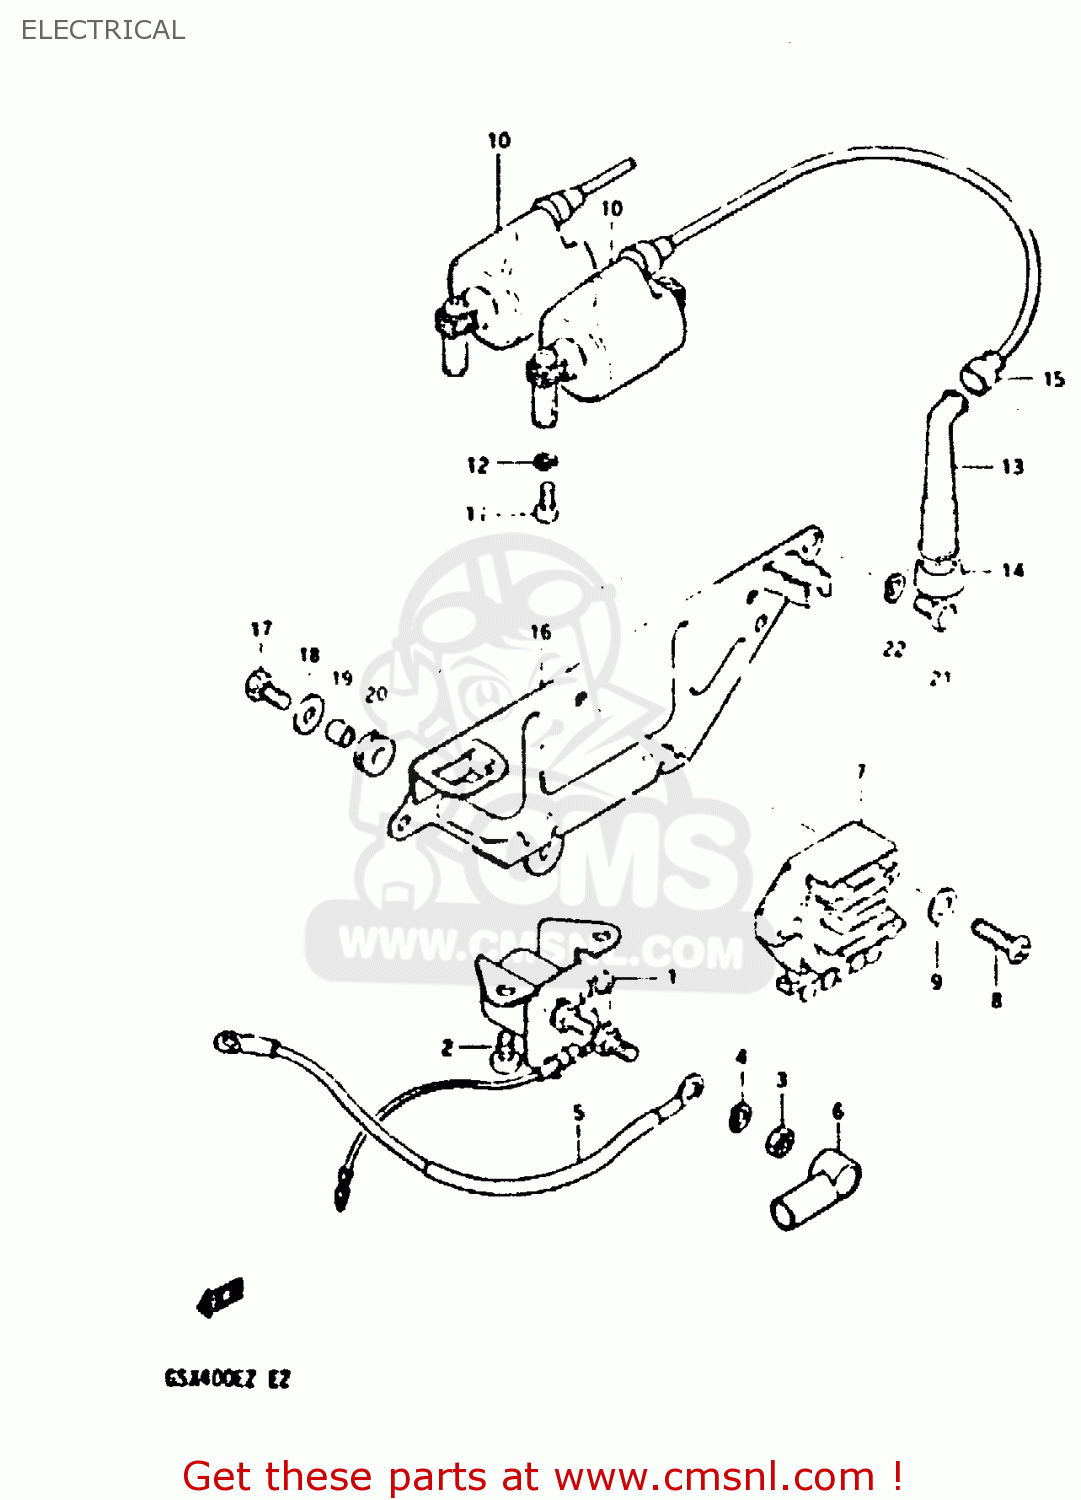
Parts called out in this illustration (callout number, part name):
1	RELAY ASSY,STARTING MOTOR
2	SCREW
3	NUT 6MM
4	LOCK WASHER
5	CORD,BATTERY MINUS
6	CAP,STARTER RELAY
7	RECTIFIER ASSEMBLY
8	SCREW
9	WASHER
10	COIL ASSEMBLY,IGNITION
11	SCREW
12	LOCK WASHER
13	CAP ASSY,SPARK PLUG
14	SEAL,SPARK PLUG
15	SEAL,SPARK PLU
16	HOLDER COMP,ELECTRONIC PARTS
17	BOLT
18	WASHER
19	SPACER (6.1X8X9.5)
20	CUSHION
21	BOLT
22	LOCK WASHER
